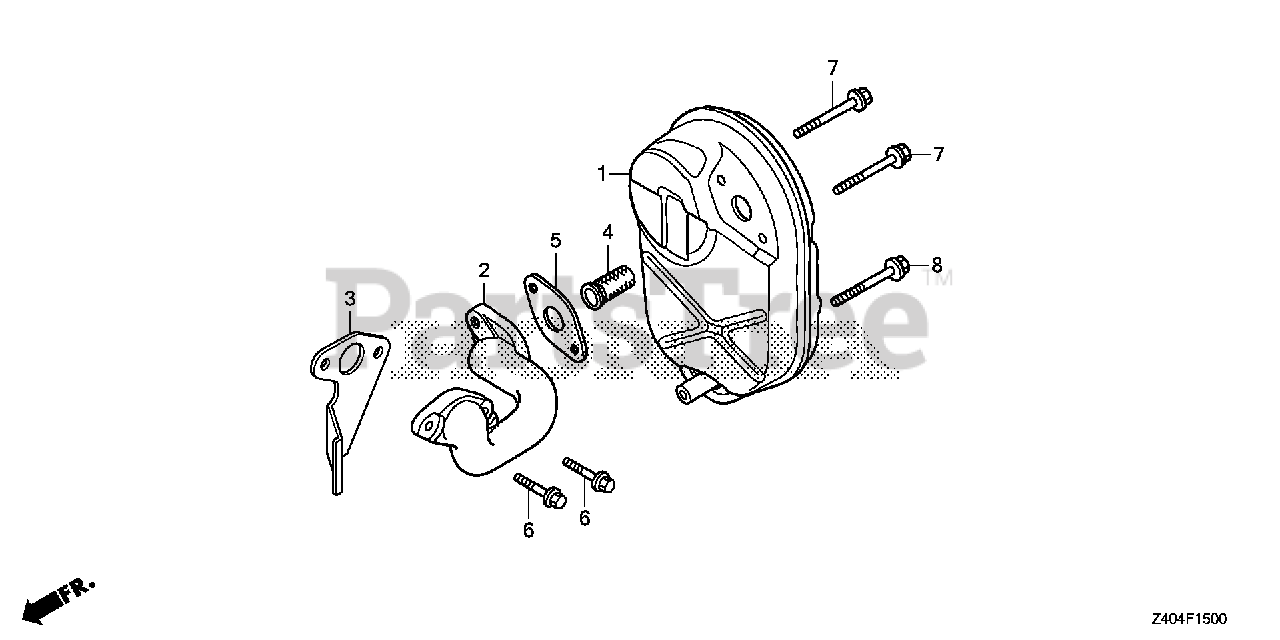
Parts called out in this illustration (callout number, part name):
3	GASKET, EX. PIPE
4	ARRESTER KIT, SPARK
5	GASKET, MUFFLER
6	BOLT, FLANGE (5X20)
7	BOLT, FLANGE (6X40)
8	BOLT, FLANGE (6X45)
